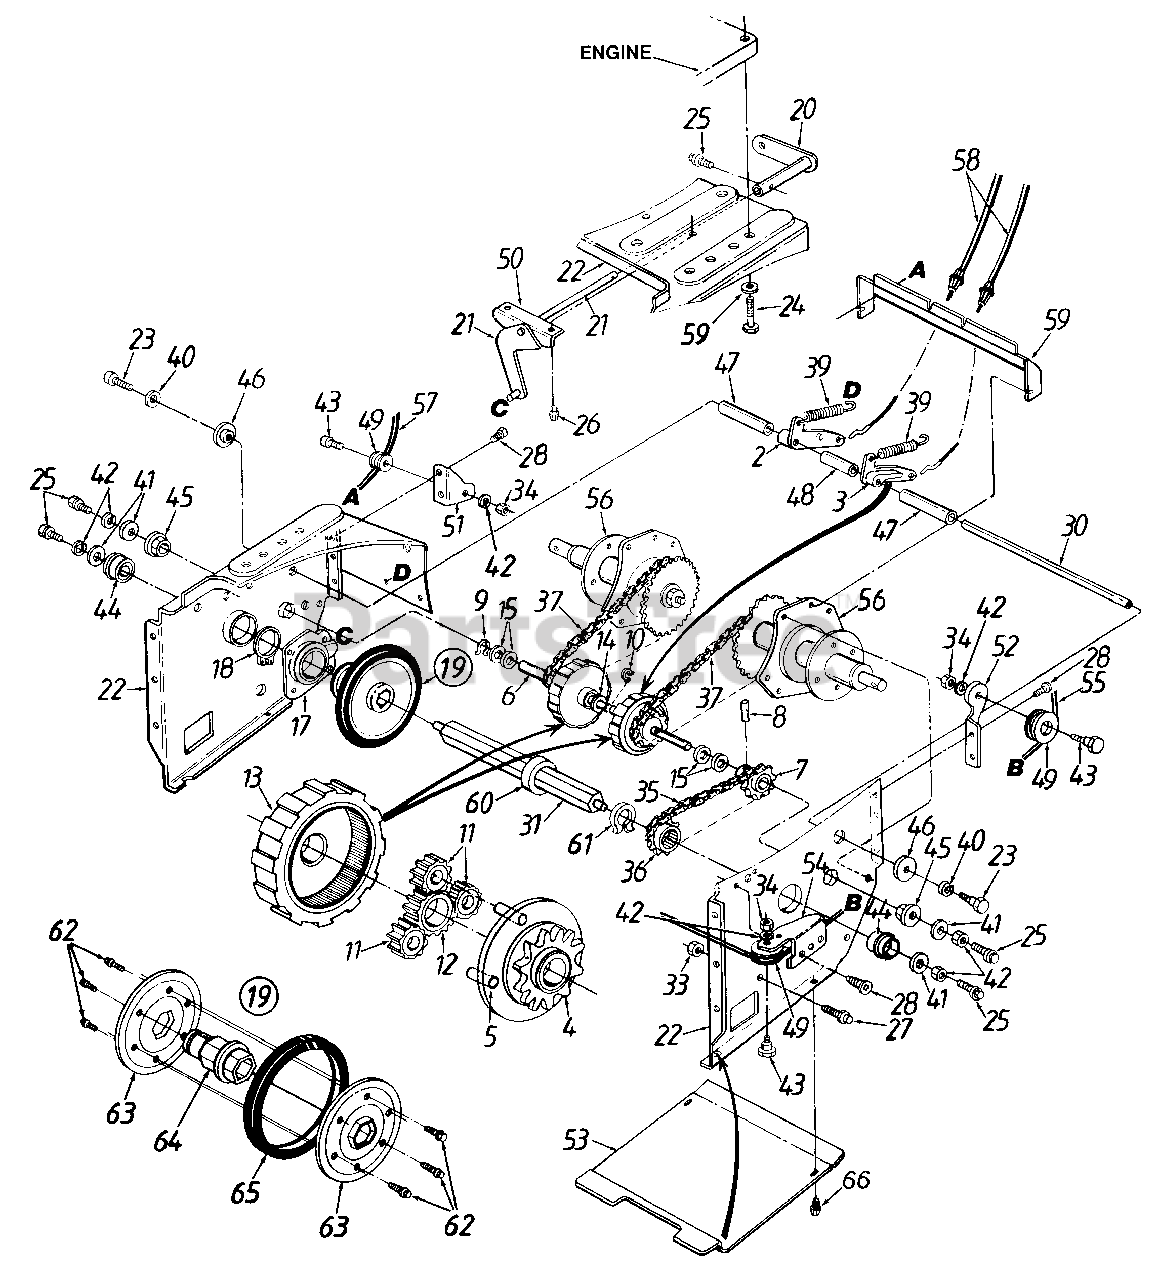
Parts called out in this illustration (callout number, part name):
2	R.H. Dog Ass'y.
3	L.H. Dog Ass'y.
4	Carrier
5	5/16" Dowel Pin
6	Drive Shaft
7	12 Tooth Sprocket
8	Spring Pin 3/16" Dia. x 1" Lg.
9	Snap Ring .56" Dia.
10	Snap Ring .625" Shaft
11	12 Tooth Gear
12	18 Tooth Gear
13	Ring Gear
14	Fl-Wash. 5/8" I.D. x 1" O.D.
15	Fl-Wash. .57" I.D. x 1.12" O.D.
17	Friction Wheel Brg. Ass'y.
18	Retaining Ring 1.375" Dia. Shaft
19	Friction Wheel Ass'y.
21	Shift Rod Ass'y.
23	Hex Bolt 5/16-18 x .75" Lg.
24	Hex L-Wash. TT-Tap Scr. 3/8-16 x 1.25" Lg.
25	Hex TT-Tap Scr. 1/4-20 x .75"
26	Hex Wash. Hd. Tap Scr. 1/4-20 x .38" Lg.
27	Hex Wash. TT-Tap Scr. 1/4-20 x 1" Lg.
28	Torx Mach. AB-Tap Scr. 1/4 x .62" Lg.
30	Actuator Shaft
31	Drive Shaft
33	Hex Nut 1/4-20 Thd.
34	Hex Jam Nut 1/4-20 Thd.
35	#420 Chain--1/2 Pitch x 30 Links (Endless)
36	11 Tooth Sprocket
37	#420 Chain--32 Links (Endless)
39	Extension Spring 2.03" Lg.
40	L-Wash. 5/16" I.D.
41	Fl-Wash. 1/4" I.D. x .93" O.D.
42	L-Wash. 1/4" I.D.
43	Shld. Bolt 5/16" Dia. x .35" Lg.
44	Ball Brg. w/Snap Ring
45	Hex Flange Bearing
46	Shld. Spacer .5" Dia. x .27" Lg.
47	Split Shld. Spacer 2.69" Lg.
48	Split Shld. Spacer 1.77" Lg.
49	Cable Roller
56	Track Hub Ass'y.
57	Drive Clutch Cable
58	Track Steer Cable w/Trigger
59	Fl-Wash. .406" I.D. x 1" O.D.
60	Spacer 1.02" I.D. x 1.25" O.D.
61	Snap Ring
62	Hex Wash. Hd. TT-Tap Scr. 1/4-20 x .5" Lg.
63	Friction Plate
64	Friction Wheel Hub
65	Friction Wheel Rubber
66	Hex Wash. Tap Scr. .38" Lg.
